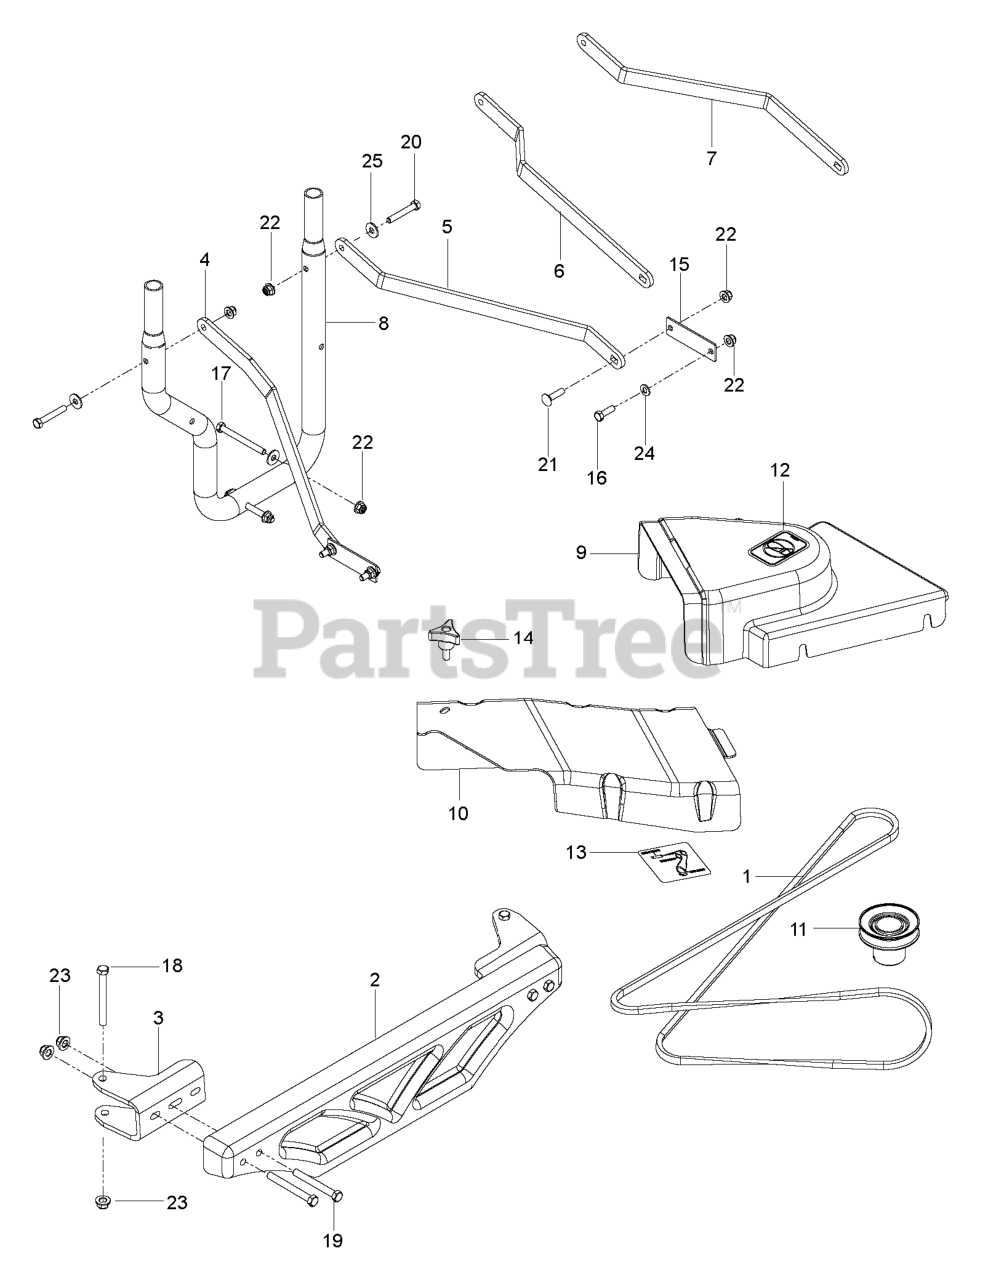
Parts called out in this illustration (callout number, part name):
1	BELT, 48/52"
2	CAST WEIGHT
3	BRACKET WEIGHT BLK
4	STRAP, SUPPORT, RT PTD
5	STRAP, SUPPORT, LT PTD
6	STRAP, SUPPORT, RT BLK
7	STRAP, SUPPORT, LT BLK
8	MOUNT.TUBE.COLLECTIONS
9	SHIELD, BELT, 48"
10	COVER, BELT
11	PULLEY, 42/48"
12	DECAL, NO STEP
13	DECAL, BELT ROUTING
14	KNOB W/STUD
15	REINFORCEMENT PLATE BLK
16	HCS 5/16C X 1
17	HCS 5/16-18 X 3 1/4
18	HCS 3/8-16 X 3-1/2 GR5 ZD
19	HCS 3/8C X 3
20	HCS 5/16-18X2
21	BOLT, CARRIAGE 5/16X1-1/4
22	5/16-18 NYLOC FLANGE NUT
23	NUT 3/8-16 HEX FLG NYLOC ZD
24	FLAT WASHER 5/16 SAE
25	WASHER 5/16 FLAT
